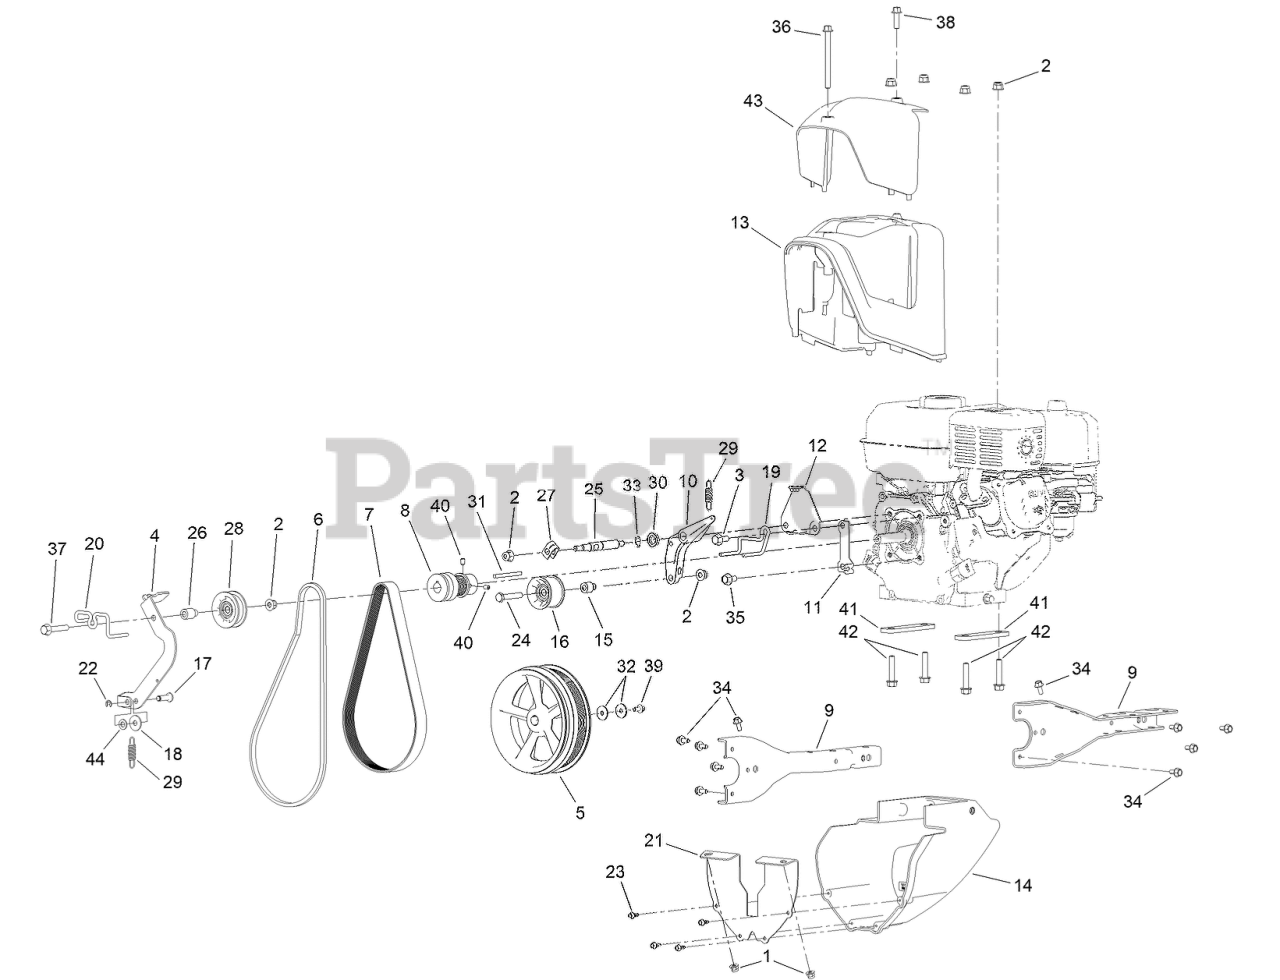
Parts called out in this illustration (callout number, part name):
1	NUT-HEX
2	NUT-HEX
3	SCREW-HHF
4	ARM-REVERSE
5	PULLEY-TRANSMISSION
6	BELT-V
7	BELT-POLY
8	PULLEY-ENGINE
9	MOUNT-ENGINE
10	ARM-FORWARD
11	BRACKET-CABLE
12	BRACKET-ENGINE
13	GUARD-UPPER
14	GUARD-LOWER
15	BUSHING-FORWARD IDLER
16	PULLEY-FORWARD IDLER
17	PIN-CLEVIS
18	WASHER-FLAT
19	GUIDE-FORWARD
20	GUIDE-REVERSE
21	GUARD-LOWER PULLEY
22	CLIP-CLEVIS
23	SCREW-HHF
24	SCREW-HHCS
26	BUSHING-REVERSE
28	PULLEY-REVERSE
29	SPRING-ARM
30	BUSHING-ARM
32	WASHER-FLAT
33	RING-RETAINING
34	SCREW-HF
35	SCREW-HF
36	SCREW-HF
37	SCREW-HHF
38	SCREW-HF
39	SCREW-HHF
40	SCREW-SET
41	PLATE-ENGINE
42	SCREW-HHF
43	COVER-PULLEY
44	WASHER-FLAT
